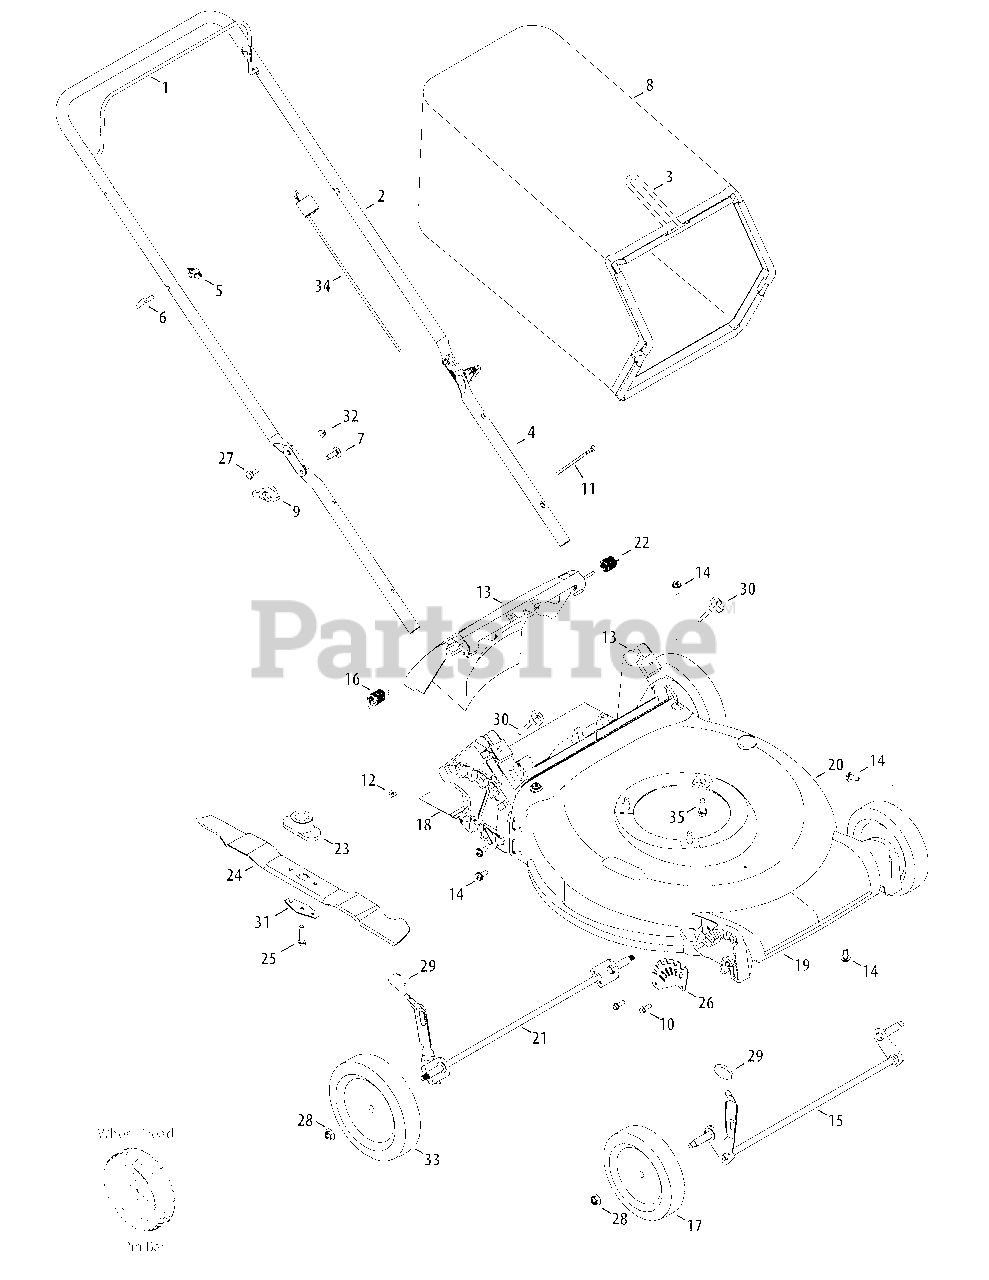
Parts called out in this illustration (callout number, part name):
1	Blade Control
2	Upper Handle
3	Grass Catcher Frame
4	Lower Handle
5	Wing Nut
6	Rope Guide
7	Carriage Screw ,5/16-18
8	Grass Bag
9	Wing Knob
10	Screw, 1/4-15 x .750
11	Cable Tie
12	Nut, Sq., 1/4-20
13	Rear Door Assembly
14	Screw, 5/16-14 x .750
15	Front Axle Assembly
16	Torsion Spring - RH
17	Front Wheel, 7 x 1.8, Bar, Gray
18	Trail Shield
19	Front Cover
20	Deck - 21"
21	Rear Axle Assembly
22	Torsion Spring - LH
23	Blade Adapter
24	Mulching Blade
25	Screw , 3/8-24 x 1.50
26	Front Height Adjuster Plate
27	Sldr. Screw, .375 x .126 x 1/4-20
28	Flange Lock Nut, 3/8-16
29	Adjustment Lever Knob
30	Wing Nut
31	Blade Bell Support
32	Nut, Flange Lock, 1/4-20
33	Rear Wheel, 8 x 1.8, Bar, Gray
34	Control Cable, 40.00"
35	TT Sems Screw, 3/8-16 x 1.0
